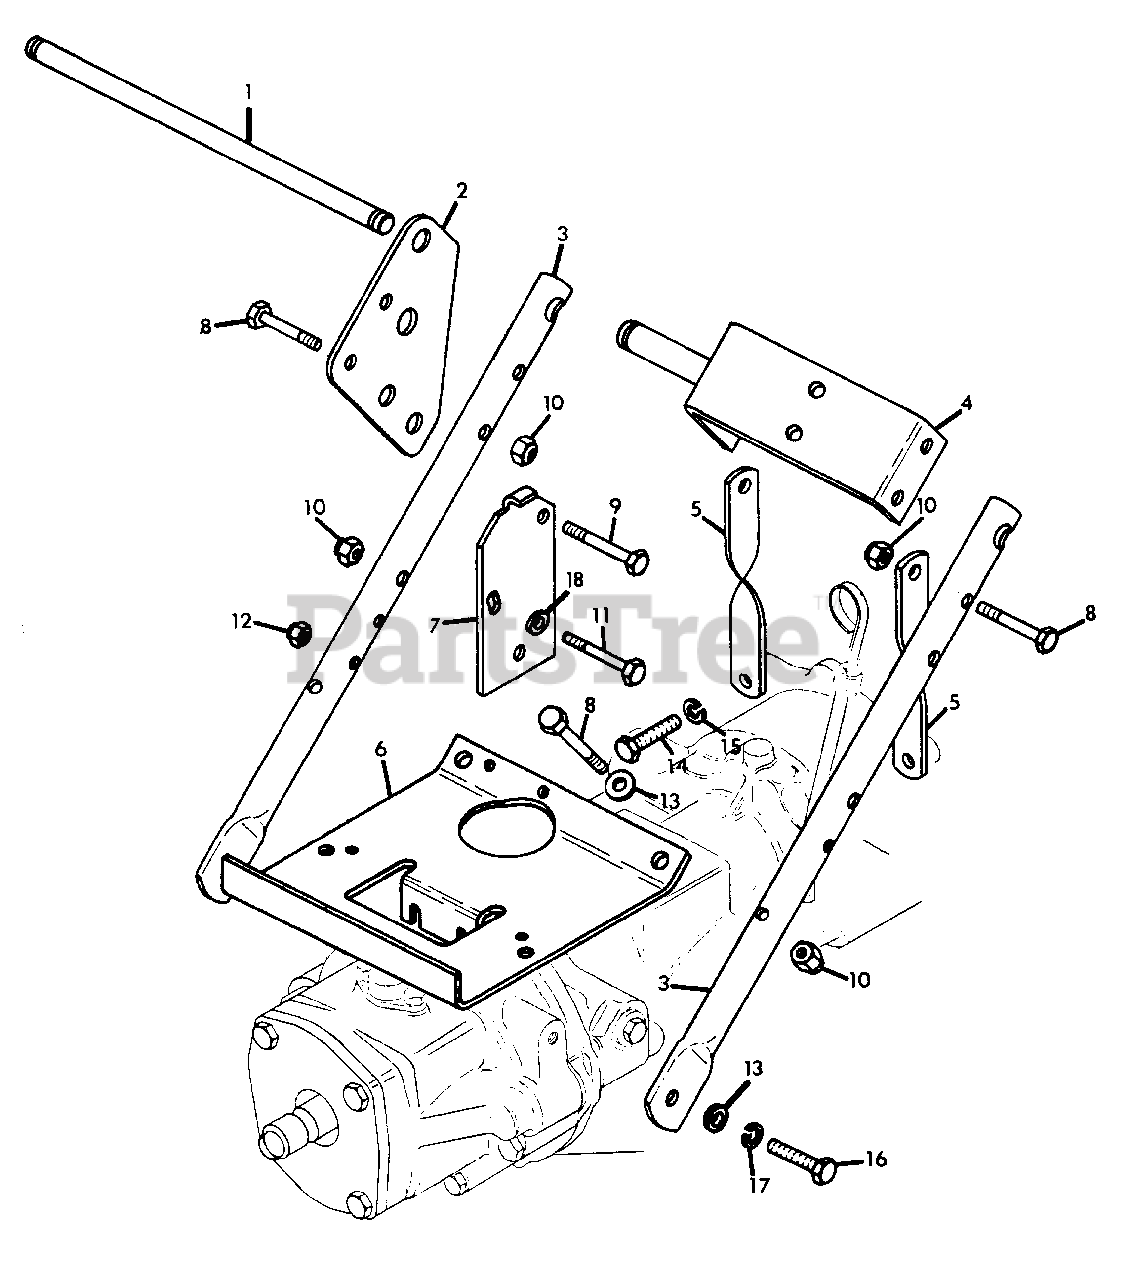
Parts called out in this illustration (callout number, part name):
1	SHAFT CROSS
2	BRACKET, INTERLOCK
3	TUBE, SUPPORT
4	WELDMENT, BRACE
5	BRACE, HANDLE
6	BOX, BATTERY
7	BRACKET, HI-LO
8	BOLT, HEX 3/8-16X2.25
9	BOLT, HEX 3/8-16X2.00
10	NUT, LOCK 3/8-16
11	BOLT, HEX 1/4-20X2.00
12	NUT, LOCK 1/4-20
13	WASHER, FLAT .406X.812X.065
14	BOLT, HEX 7/16-14X1.50
15	WASHER, LOCK 7/16
16	BOLT, HEX 3/8-16X1.00
17	WASHER, LOCK 3/8
18	WASHER, FLAT .281X.625X.065
